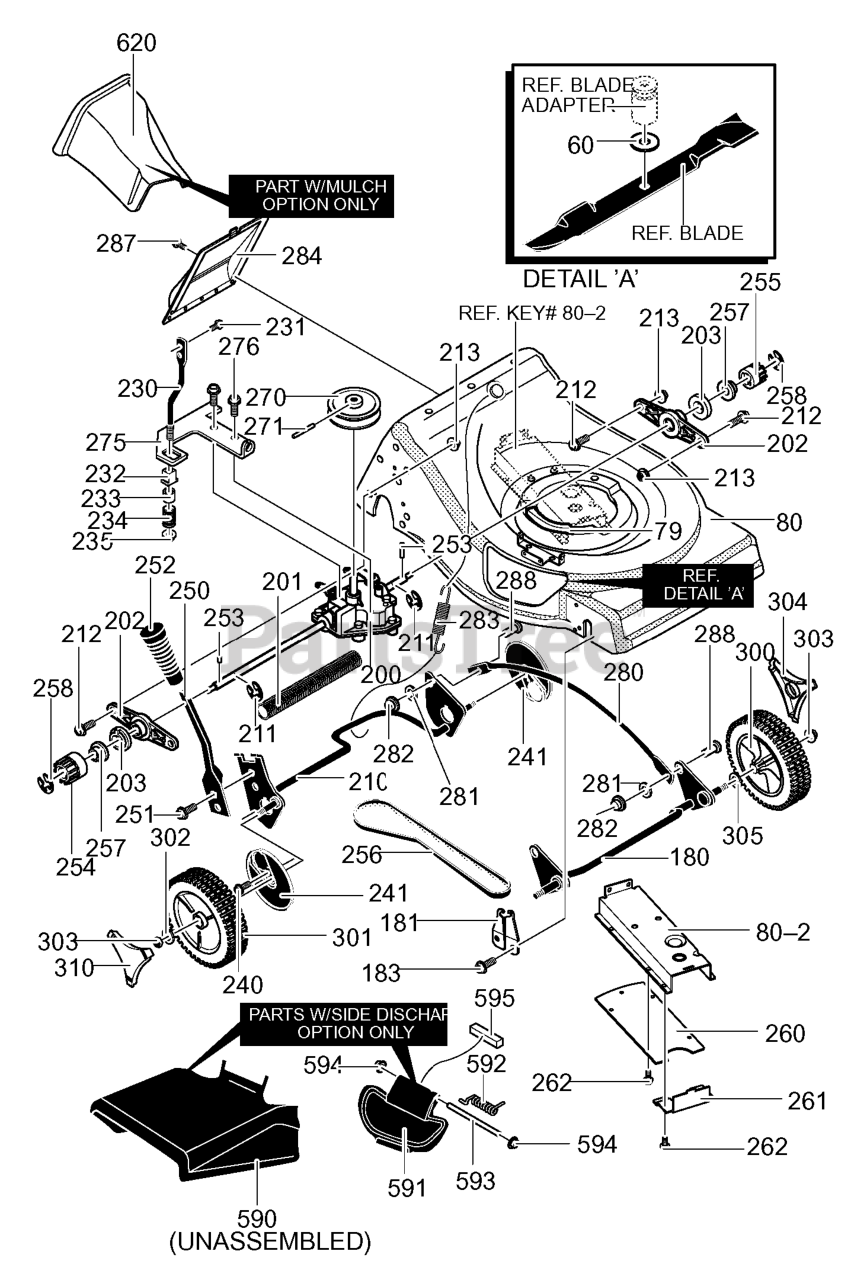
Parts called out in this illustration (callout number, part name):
80	ASSY, FRAME
80-2	GUARD, BELT
180	CROSSBAR, FRONT
181	BUSHING
200	TRANSMISSION
201	SHIELD, AXLE
202	SUPPORT, AXLE
203	BEARING, LIFTER
210	ASSY, CROSSBAR
211	E-RING
212	SCREW
230	SUPPORT, SPRING
232	BUSHING
234	SPRING
235	NUT, 5/16-18
241	DUST COVER
250	LEVER, SPRING
252	KNOB, HEIGHT ADJ
253	PIN, DRIVE
254	GEAR, PINION RIGHT
255	GEAR, PINION LEFT
256	BELT, V
257	WASHER, FLAT
258	E-RING
260	COVER, BELT GUARD
261	COVER, FRONT BELT
271	PIN, SPRING
275	BRACKET, CABLE
280	LINK, LIFTER 21
281	NUT, PUSH ON
282	PUSH ON CAP
283	SPRING, EXTENSION
284	COVER, REAR
288	PIN, CLEVIS
300	TIRE & RIM
301	WHEEL, DRIVE
302	WASHER, FLAT
304	HUB CAP
310	HUB CAP
590	DEFLECTOR, CHUTE
591	COVER, MULCH
592	SPRING, TORSION
593	ROD, PIVOT
594	CAP, PUSH ON
595	SEAL, FOAM
620	PLUG, MULCHER
